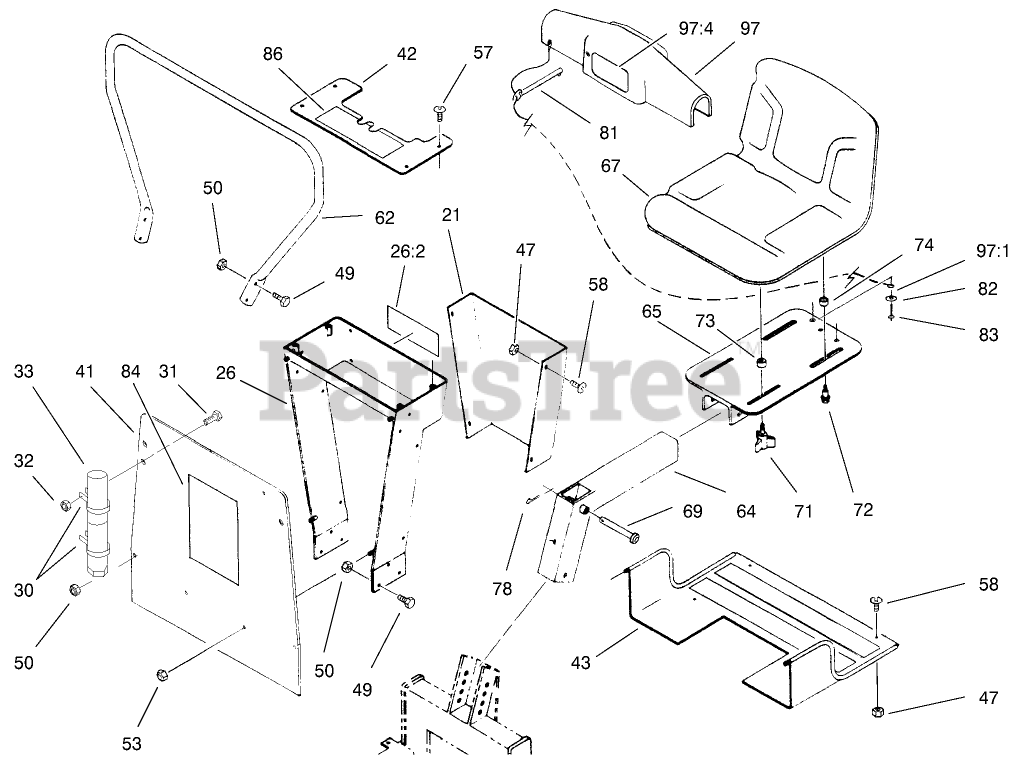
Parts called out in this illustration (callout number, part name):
21	GUARD-HOSE
26	VALVE MOUNT ASM
26:2	DECAL-WARNING
30	CLAMP-R
32	NUT-LOCK, NI
33	TUBE-MANUAL
41	PANEL-FRONT
42	COVER-VALVE
43	FOOT PLATE ASM
47	NUT-LOCK
49	SCREW-HH
50	NUT-LOCK, NI
53	NUT-LOCK, NI
57	SCREW
62	HANDLE-GUARD
64	SEAT MOUNT ASM
65	SEAT PLATE ASM
67	SEAT
69	PIN-CLEVIS
72	BOLT-SHOULDER
73	SPACER-NYLON
74	SPACER-NYLON
78	PIN-COTTER
81	PIN-COTTERLESS
82	Washer
83	RIVET-POP
84	DECAL - SIDE
86	DECAL-PANEL, CONTROL
97	CLIP ASM-BACKHOE
97:1	LANYARD
97:4	DECAL-CLIP
